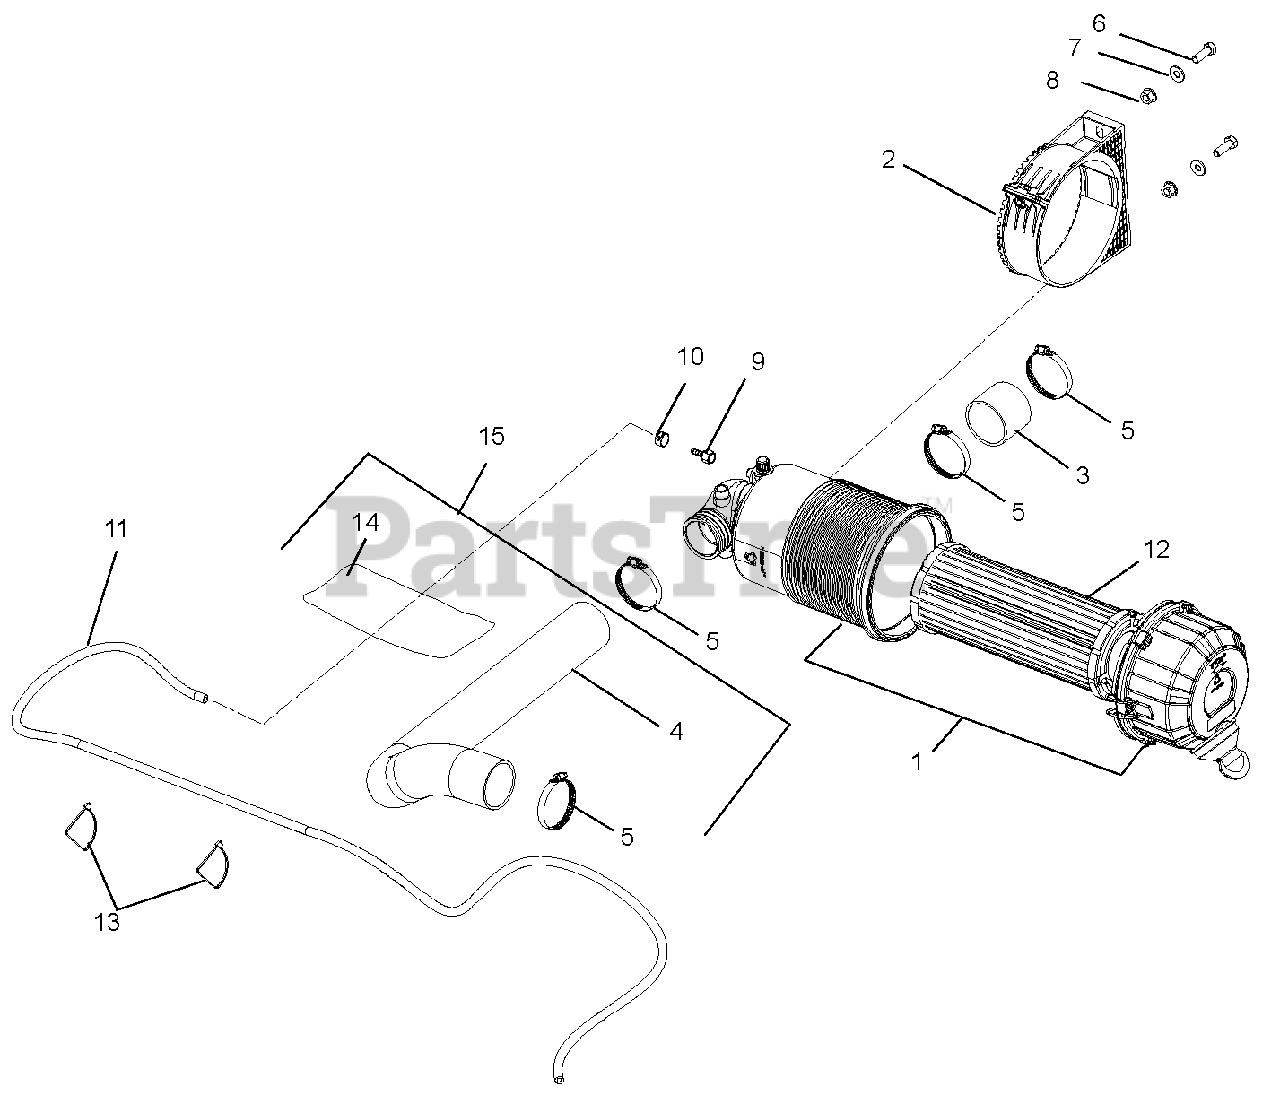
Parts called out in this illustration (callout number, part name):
1	ASSEMBLY, AIR CLEANER EPA
2	CLAMP, AIR CLEANER BRACKET
3	INTAKE AIR FILTER COUPLER
4	INTAKE TUBE, ENGINE
5	CLAMP, HOSE, WRM DRV, 1.81 X 2.75
6	BOLT, HEX .31-18 X 1.00 GR5 YWZC
7	WASHER, FLAT STEEL .312 X .734 X .065 YWZC
8	HEX NUT, LOCKING TOP FLANGE .31-18 YWZC
9	FITTING, 1/8-27 NPT, 3/16 BARB
10	CLAMP, FUEL LINE, 3/16"
11	HOSE, .188 LOW-PERM 34"
12	FILTER AIR OUTER ELEMENT
13	CABLE TIE WITH TREE
14	TAPE FOIL 39"
15	ASM, INTAKE HOSE & HEAT TAPE (Includes items #4 & #14 assembled)
